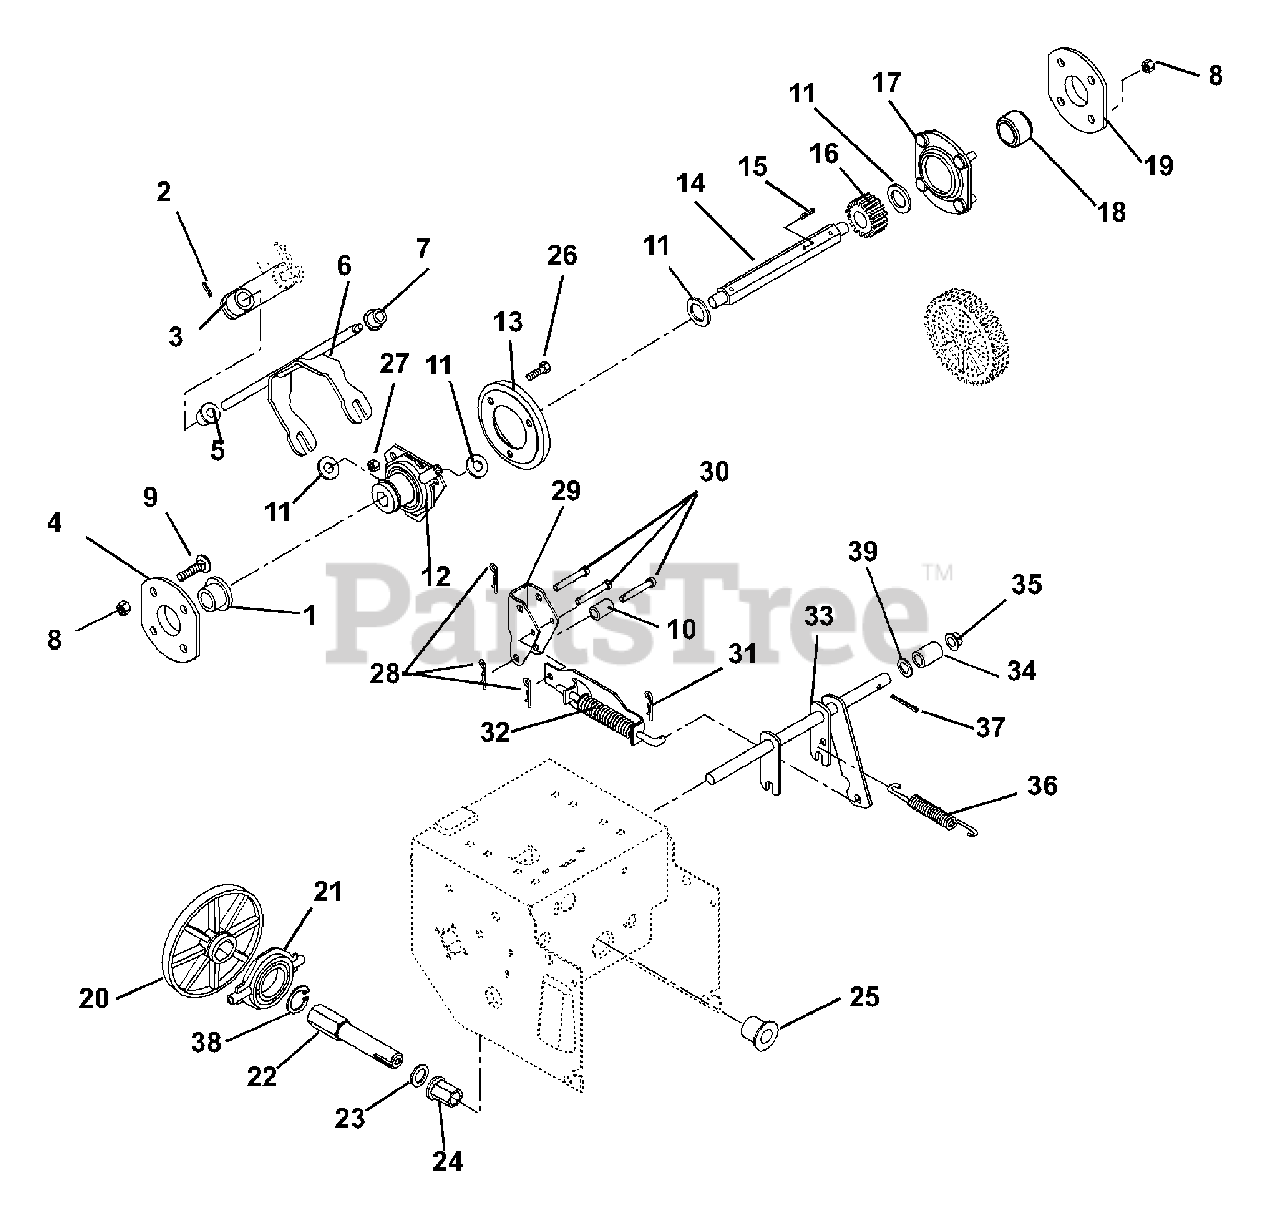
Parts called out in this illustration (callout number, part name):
1	BSHG-FLG .500X.750X.625X.937
2	PIN-ROLL .156X.88
3	WELDMENT, SPEED CONTROL ARM
4	FLANGE AND BUSHING
5	BSHG-FLG .500X.625X.500X.750
6	FORK-SPEED
7	BSHG-FLG .325X.444X.440X.560
8	NUT-LK-DUAL FACE 10-24 YWZC
9	BLT-RDHDSQSHK #10-24X.38 GR2YW
10	SPACER .325 X.625 X.455
11	WSHR-FL-STL .505X1.00X.062YWZC
12	SHIFT CARRIER
13	DISC, FRICTION - 730 MAT'L
14	SHAFT, HEX
15	PIN-ROLL .125X.88
17	BEARING FLANGE
18	BRG-BALL .437X1.375X.437
19	BEARING FLANGE
20	FRICTION PLATE
21	BEARING ASSEMBLY
22	SHAFT, SPINDLE - COMPACT SNOW
23	WSHR-THRST .625 X 1.0 X .03
24	BSHG-FLG .625X.875X1.750X1.188
25	BSHG-FLG .875X1.25X.75X1.50HX
26	@BLT-HEX .25-20X.50 GR5 YWZC
27	@NUT-LK-CTR .25-20 YWZC
28	PIN-HAIR INT .06X.18X.77
29	BRACKET, TRACTION ARM
30	PIN,CLEVIS .243/.248 X 1.38 YZ
31	PIN-HAIR INT .08X.18X1.18 YWZC
32	TRACTION CLUTCH ASSY
33	CLUTCH FORK
34	SPACER .504X.748X.321
35	CAP, .50 ROD YWZC
36	SG-TENS .063X.44X1.56
37	@PIN-CTR .12X1.00 EXTPRSQCT YZ
38	RG-RTNG-EXT 1.250X.050
39	@WSHR-FL-STL.531X1.06X.095YWZC
